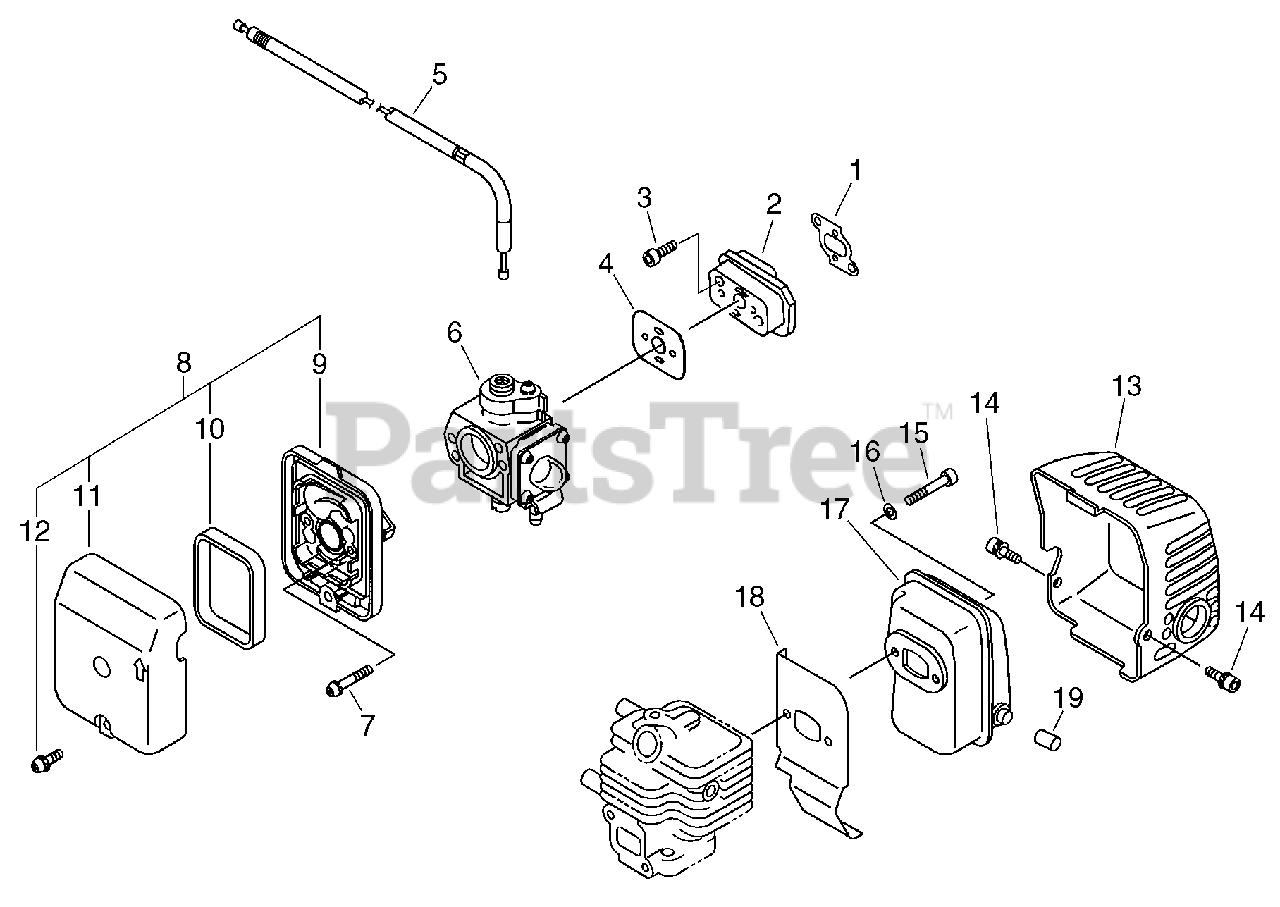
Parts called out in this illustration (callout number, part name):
1	GASKET, INTAKE
2	INSULATOR, INTAKE
3	SCREW - 5X25
4	GASKET, INTAKE
5	CABLE, THROTTLE
6	CARBURETOR
7	SCREW - 5X50
8	AIR CLEANER ASSY
9	CASE, AIR FILTER
10	FILTER, AIR
11	COVER, AIR FILTER
12	SCREW - 5X16
13	COVER, EXHAUST
14	SCREW - 5X8
15	SCREW - 5X55
16	WASHER - 5
18	SHIELD, EXHAUST
19	PIPE, EXHAUST
